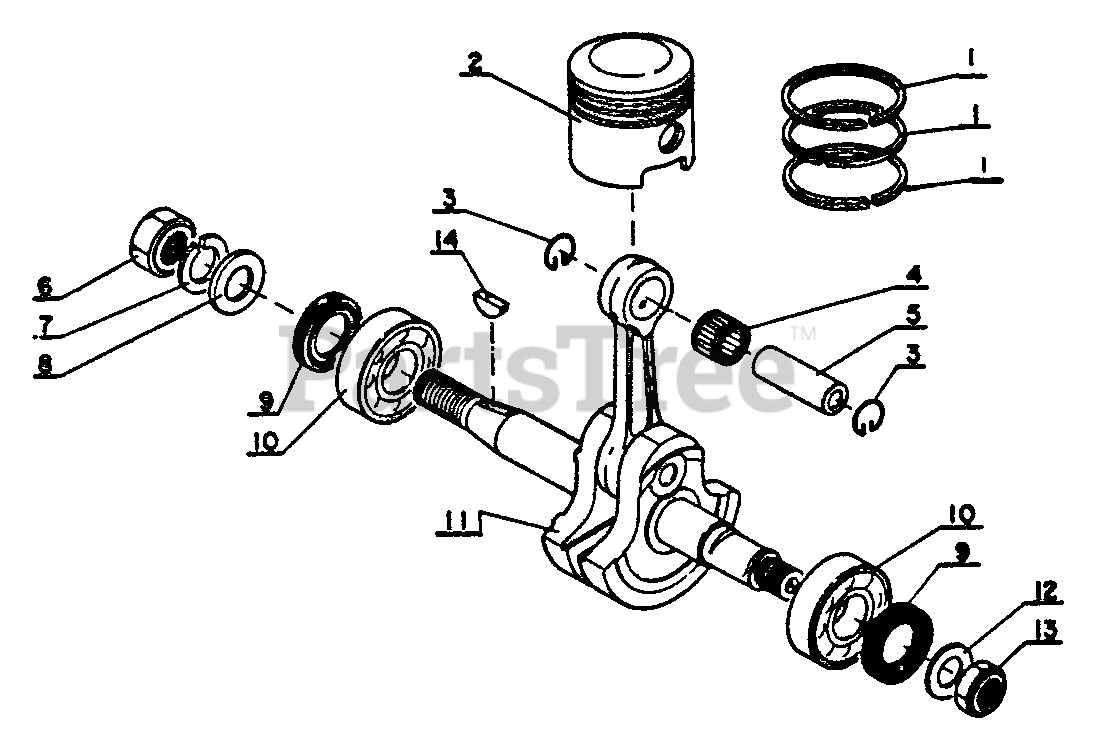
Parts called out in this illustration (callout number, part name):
1	RING, PISTON
2	PISTON
3	RING, RETAINING - 8
4	BEARING, NEEDLE
5	PIN, PISTON
7	LOCKWASHER
9	SEAL, OIL
10	BEARING, BALL - 6202
11	CRANKSHAFT ASSY
12	WASHER, CLUTCH
